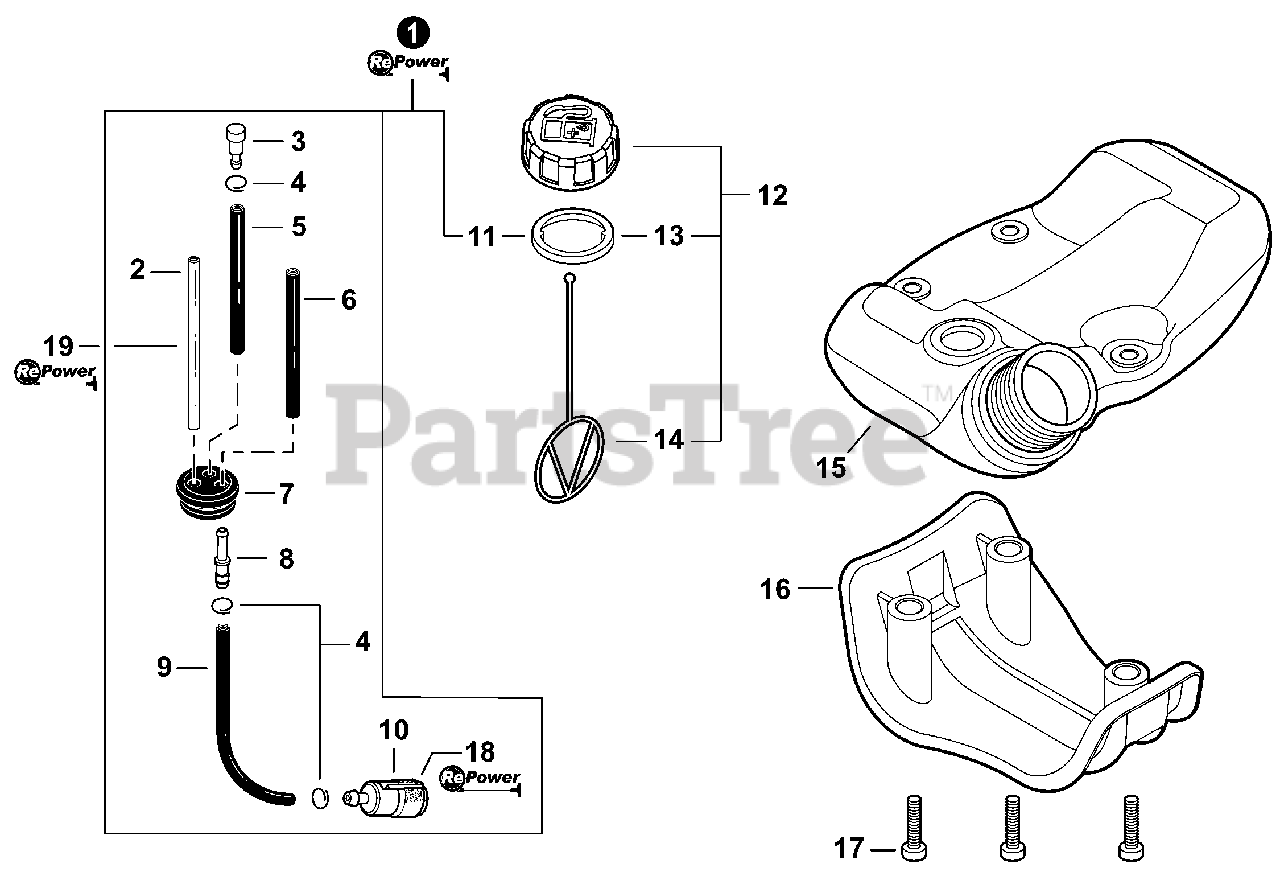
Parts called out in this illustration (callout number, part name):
1	FUEL SYSTEM KIT
2	PIPE, FUEL 3×6×80 CLEAR
3	VENT ASSY
4	CLIP Ø6
5	PIPE, FUEL 3×5×90 BLACK
6	PIPE, FUEL 3×5×74 BLACK
7	GROMMET, FUEL Ø5
8	CONNECTOR, PIPE Ø5ר3.5
9	PIPE, FUEL 3×5×110 BLACK
10	FILTER, FUEL
11	GASKET, FUEL CAP
12	CAP ASSY, FUEL
13	GASKET, FUEL CAP
14	CONNECTOR, CAP L= 123
15	TANK, FUEL
16	GUARD, FUEL TANK
17	BOLT, TORX 5×25
18	TUNE-UP KIT - REPOWER
19	BULK PIPE - 3×6 MM CLEAR (4 PIECES×2 M)
